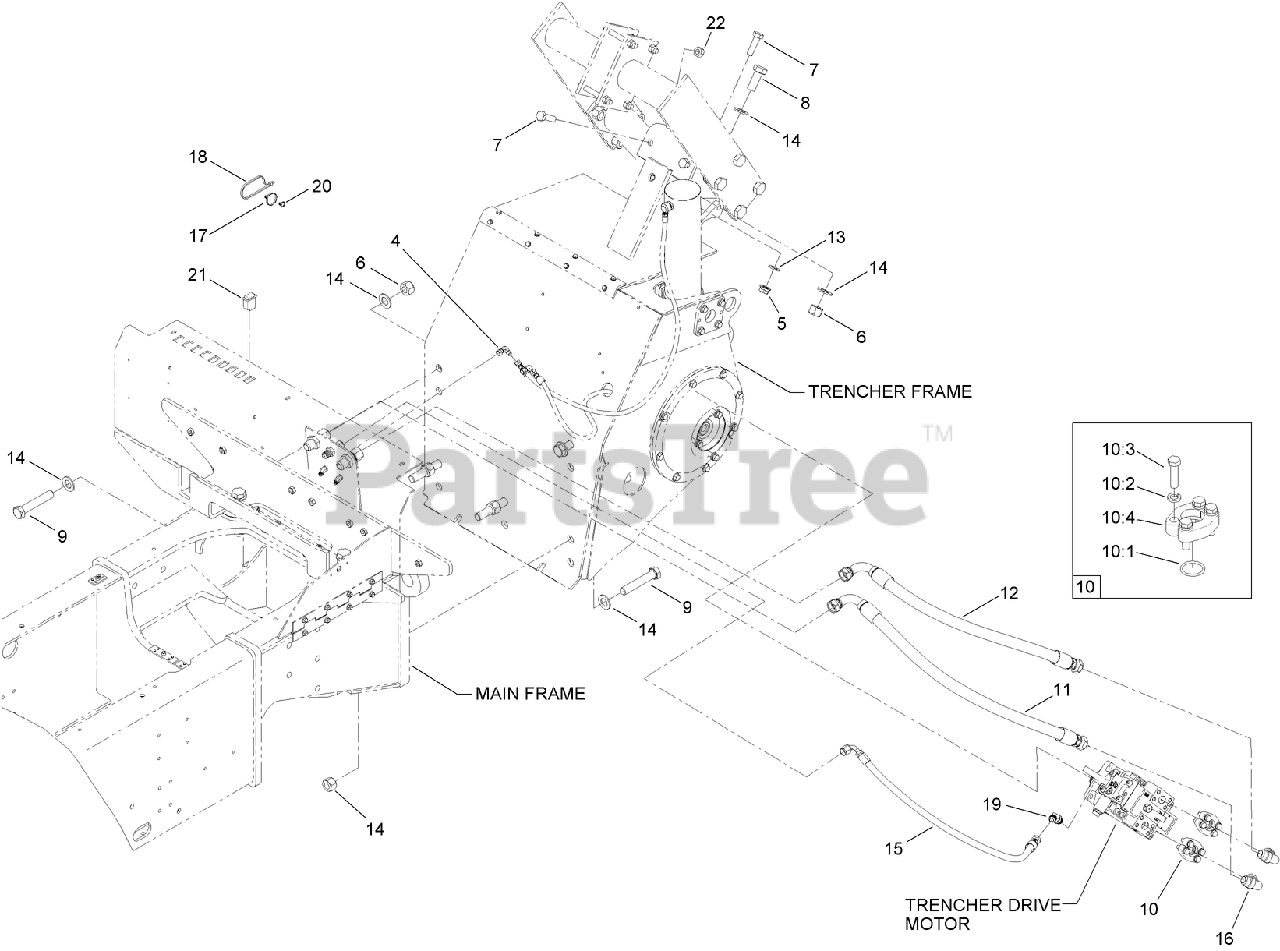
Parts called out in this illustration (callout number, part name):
4	ELBOW-SWIVEL, 90 DEG
5	NUT-HEX FLANGE
7	SCREW-HH
9	SCREW-HH
10	FLANGE KIT (CODE 62)
10:1	O-RING
10:2	WASHER-LOCK
10:3	SCREW-HH
11	HOSE ASM
12	HOSE ASM
13	WASHER-FLAT
15	HYD HOSE ASM
16	FITTING-ELBOW
17	STRAP-TIE
18	STRAP-TIE
19	FITTING-ELBOW, 45 DEG
20	STRAP-TIE, NYLON
21	SWITCH-ROCKER, 2 POLE (ON/OFF)
22	NUT-LOCK
